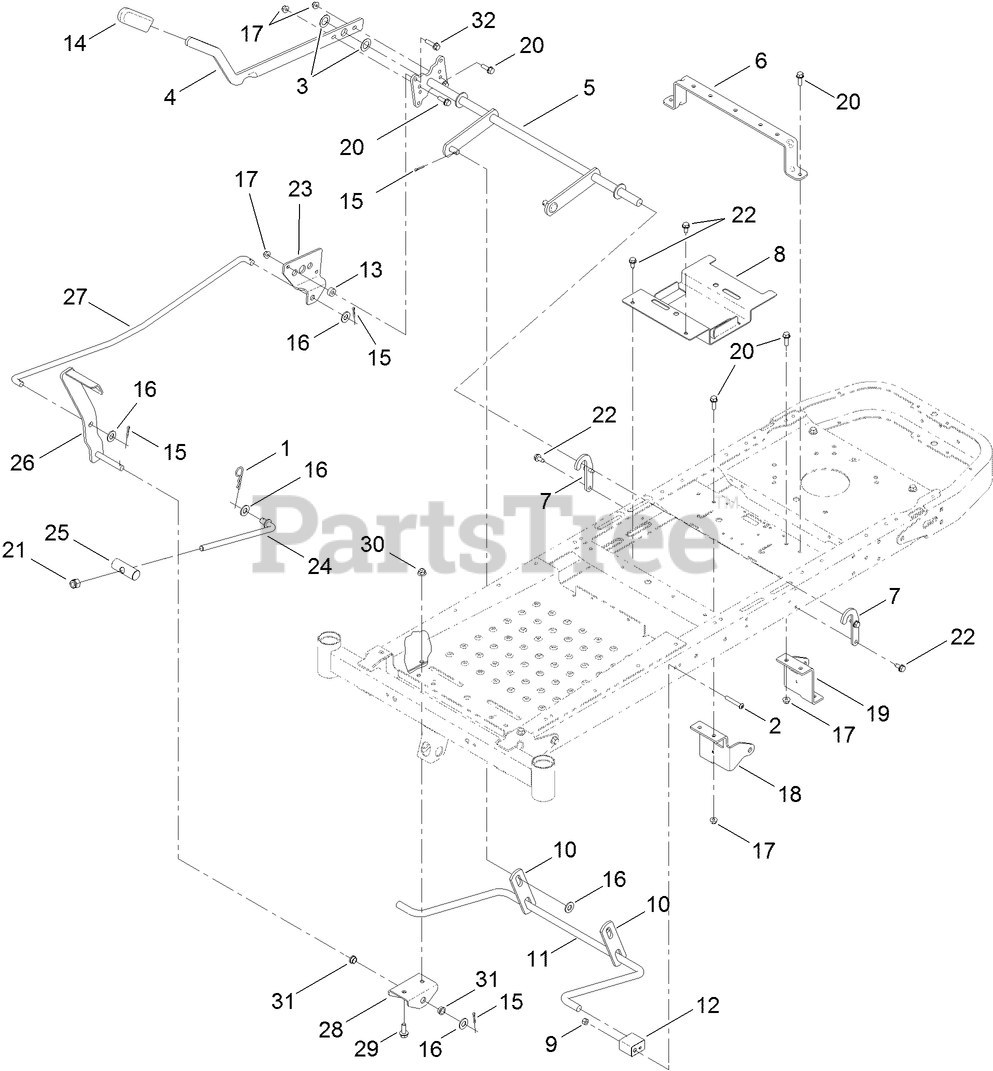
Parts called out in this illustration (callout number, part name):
1	PIN-COTTER
2	SCREW-HSBH
3	WASHER-THRUST
4	LEVER-LIFT
6	BRACE-SEAT, REAR (NARROW)
7	BRACKET-LIFT
8	BRACKET-BATTERY
9	NUT-LOCK, NI
10	LINK-LIFT
11	ARM-LIFT, REAR
12	BLOCK-PIVOT
13	SPACER
14	GRIP-LEVER
15	PIN-COTTER
16	WASHER-FLAT
17	NUT-HF, NI
18	MOUNT-HYDRO, FRONT (RH)
20	SCREW-HHF
21	NUT-HEX
22	SCREW-HWHTF
23	PLATE-FOOTLIFT
25	PIN-PIVOT
27	ROD-FOOTLIFT
28	BRACKET-FOOTLIFT
29	SCREW-HHF
30	NUT-HF, NI
31	BUSHING-FLANGE
32	SCREW-HHF
